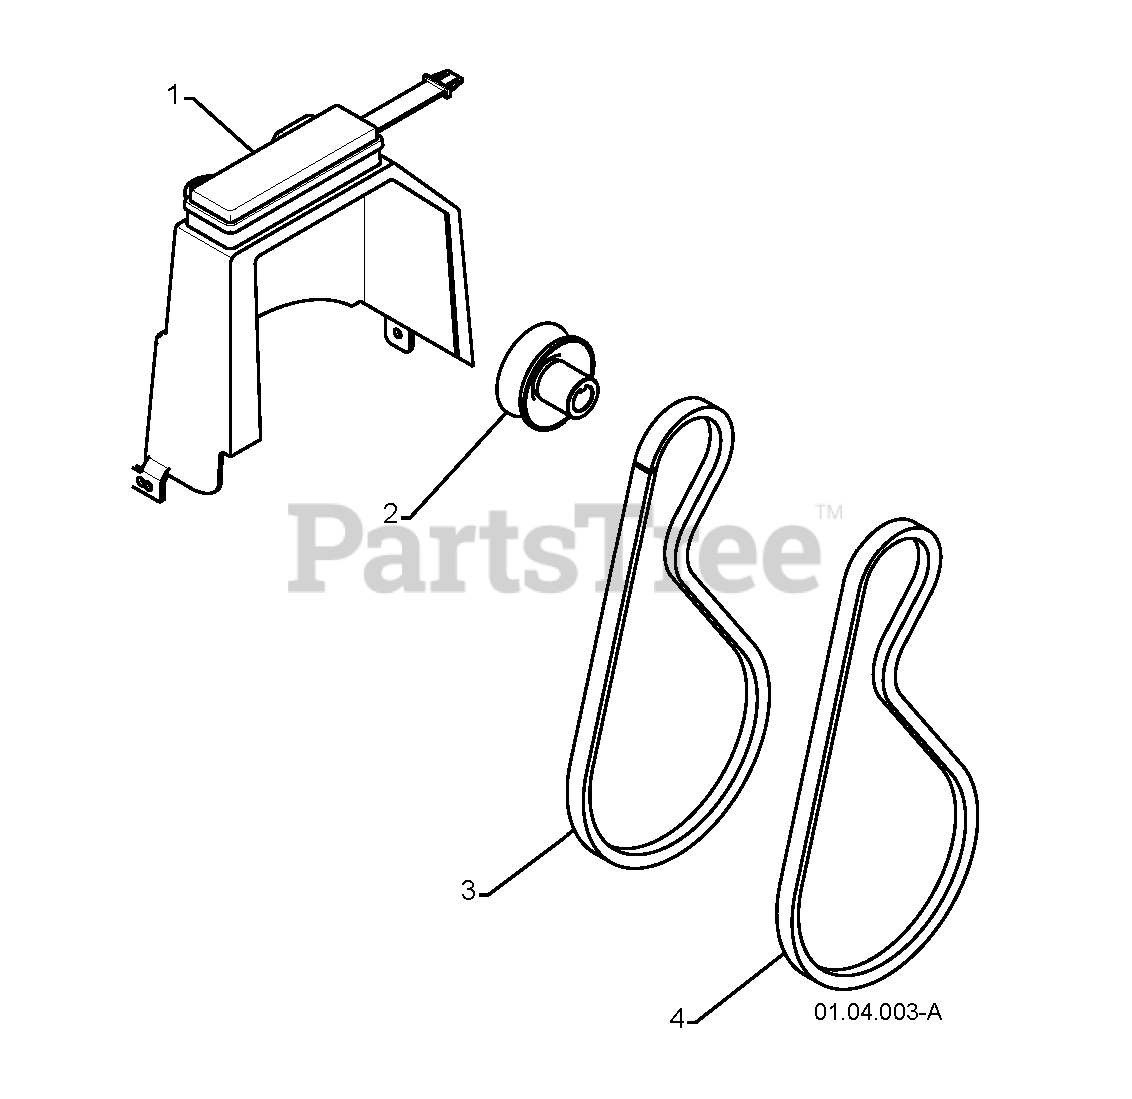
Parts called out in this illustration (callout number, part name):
1	COVER.ASM.BELT/STORAGE
2	PULLEY, ENGINE IMPELLER DRIVE
3	V-BELT TRACTION 34.25
4	BELT.V.IMPELLER
